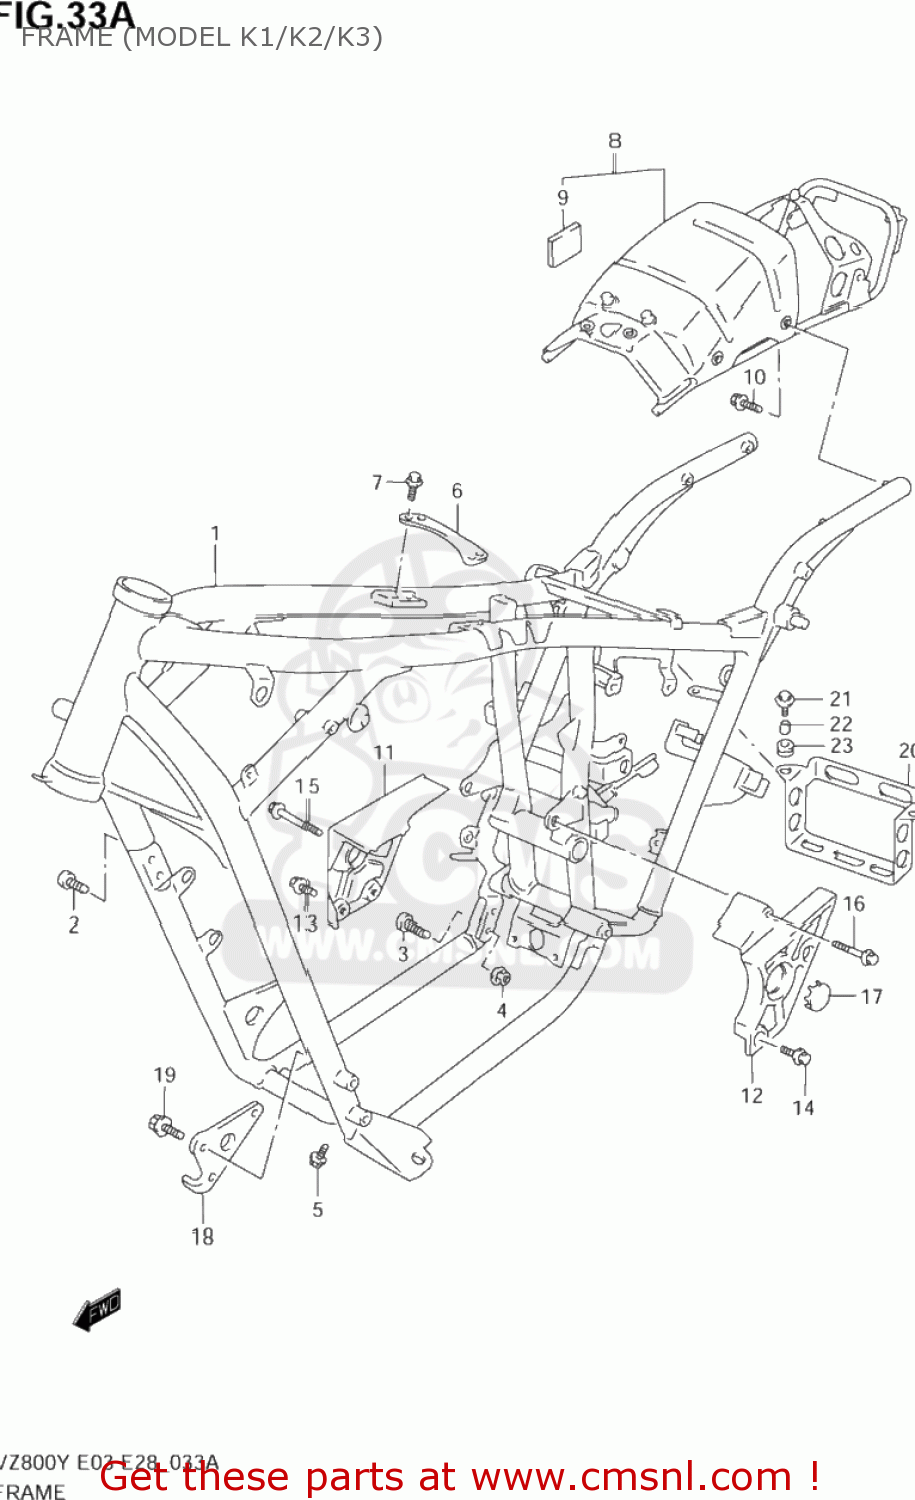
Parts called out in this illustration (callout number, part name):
1	FRAME(BLACK)
2	BOLT
3	BOLT
4	NUT
5	BOLT
6	PLATE,FRAME BODY
7	BOLT(8X16)
8	BRACE ASSY,RR FRAME
9	PAD
10	BOLT, FRONT
11	COVER,PIVOT,R
12	COVER,PIVOT,L
13	BOLT(8X16)
14	BOLT,PIVOT COVER
15	BOLT(8X16)
16	BOLT,PIVOT COVER UPR,L
17	CAP,RR SWINGING ARM PIVOT,R
18	PLATE,ENGINE MOUNT NO.1,L
19	BOLT
20	HOLDER,BATTERY
21	BOLT(6X16)
22	SPACER(6.5X9X8)
23	CUSHION
